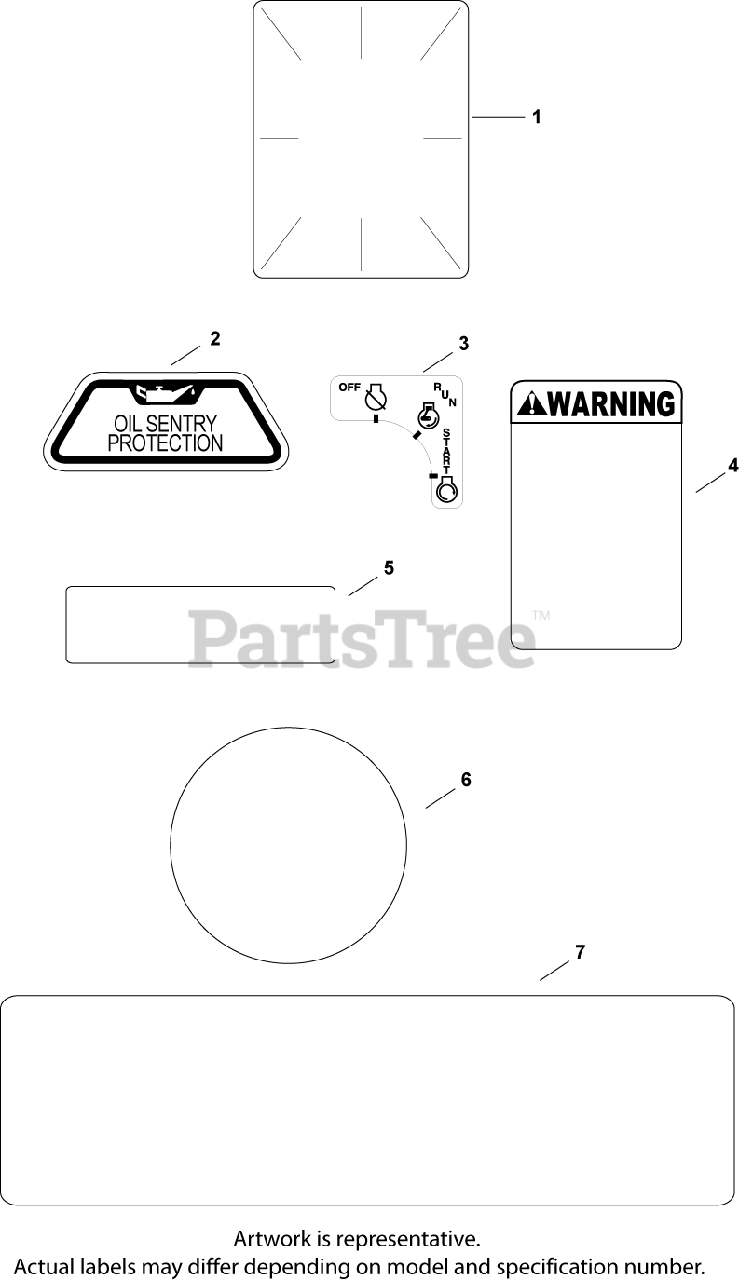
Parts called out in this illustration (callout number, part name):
1	DECAL, CLEAR LAMINATE USE 25 113 70-S
2	DECAL, OIL SENTRY - (#DSC)
3	DECAL, KEY SWITCH
4	DECAL, CO WARNING
5	DECAL, LP SMARTSPARK - DISC.
6	LABEL, (ROUND KOHLER GOLD)-USE 24 113 18
7	DECAL, COMMAND PRO (GASEOUS)
